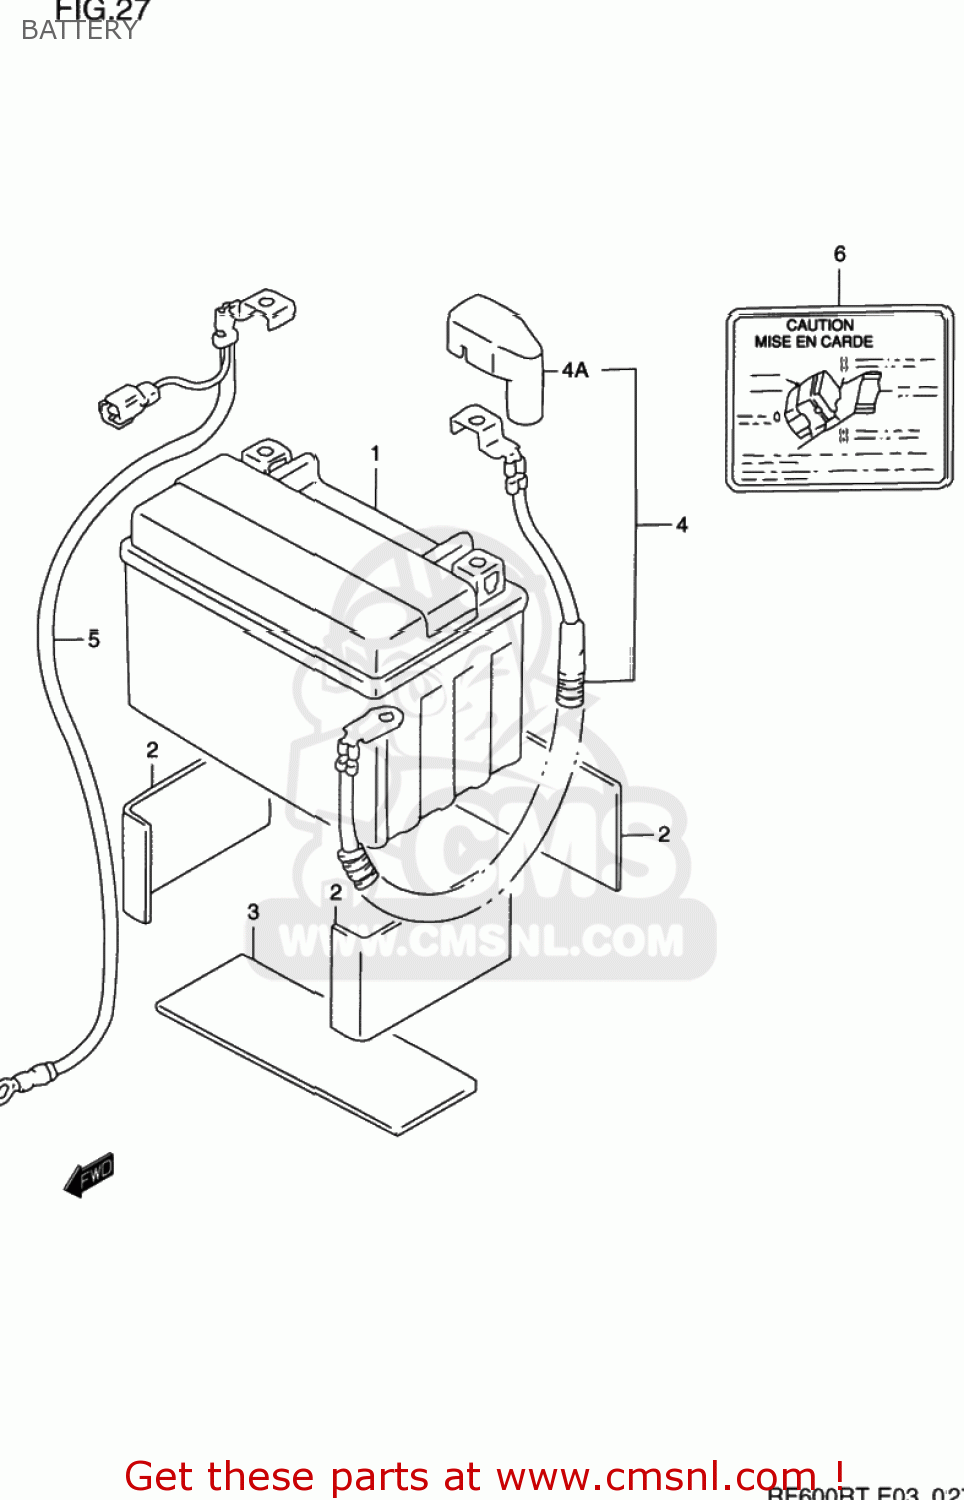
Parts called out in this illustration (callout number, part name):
1	BATTERY ASSEMBLY (12V) YTX
2	PROTECTOR(170X95X3.0)
3	PROTECTOR(170X95X3.0)
4	WIRE,BATTERY PLUS LEAD
4A	CAP,BATTERY PLUS
5	WIRE,BATTERY MINUS
6	PLATE,BATTERY CAUTION
